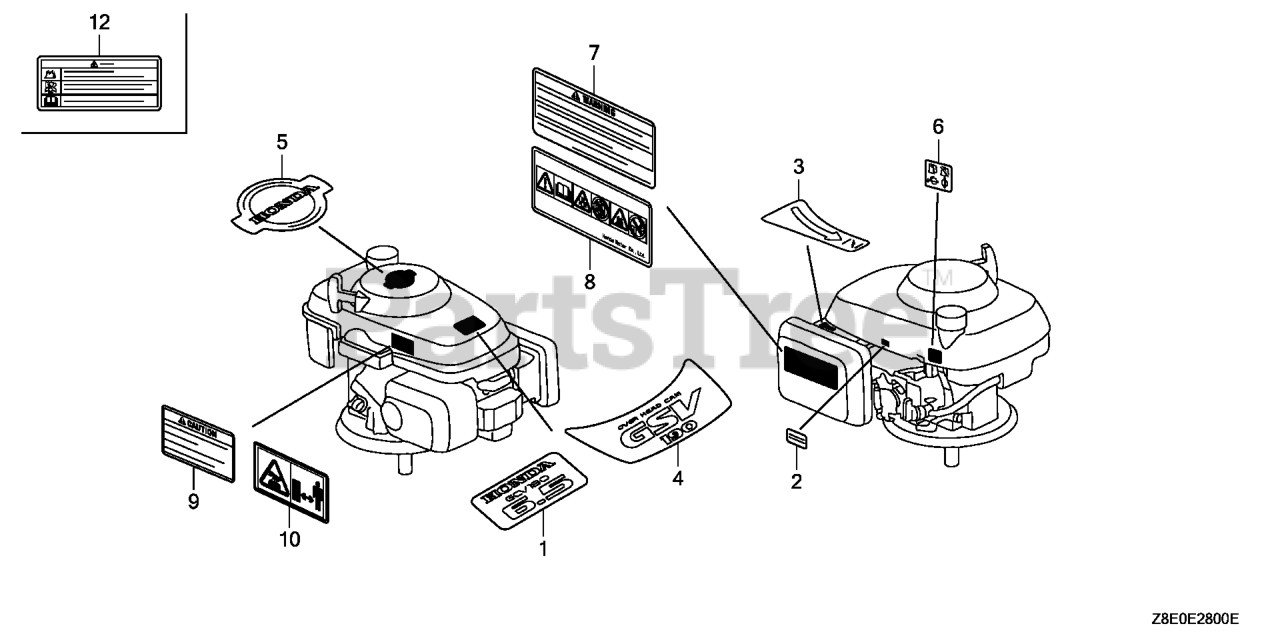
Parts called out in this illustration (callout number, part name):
1	MARK, EMBLEM (GSV190 6.5)
2	LABEL, WARNING (NOT CERTIFIED FOR SALE)
4	MARK, EMBLEM (GSV190)
5	MARK, RECOIL COVER
6	MARK, FUEL PETCOCK CAUTION
7	MARK, OPERATOR CAUTION (ENGLISH)
8	MARK, OPERATOR CAUTION
9	MARK, EX. CAUTION (ENGLISH)
10	MARK, EX. CAUTION (PICTOGRAPH)
